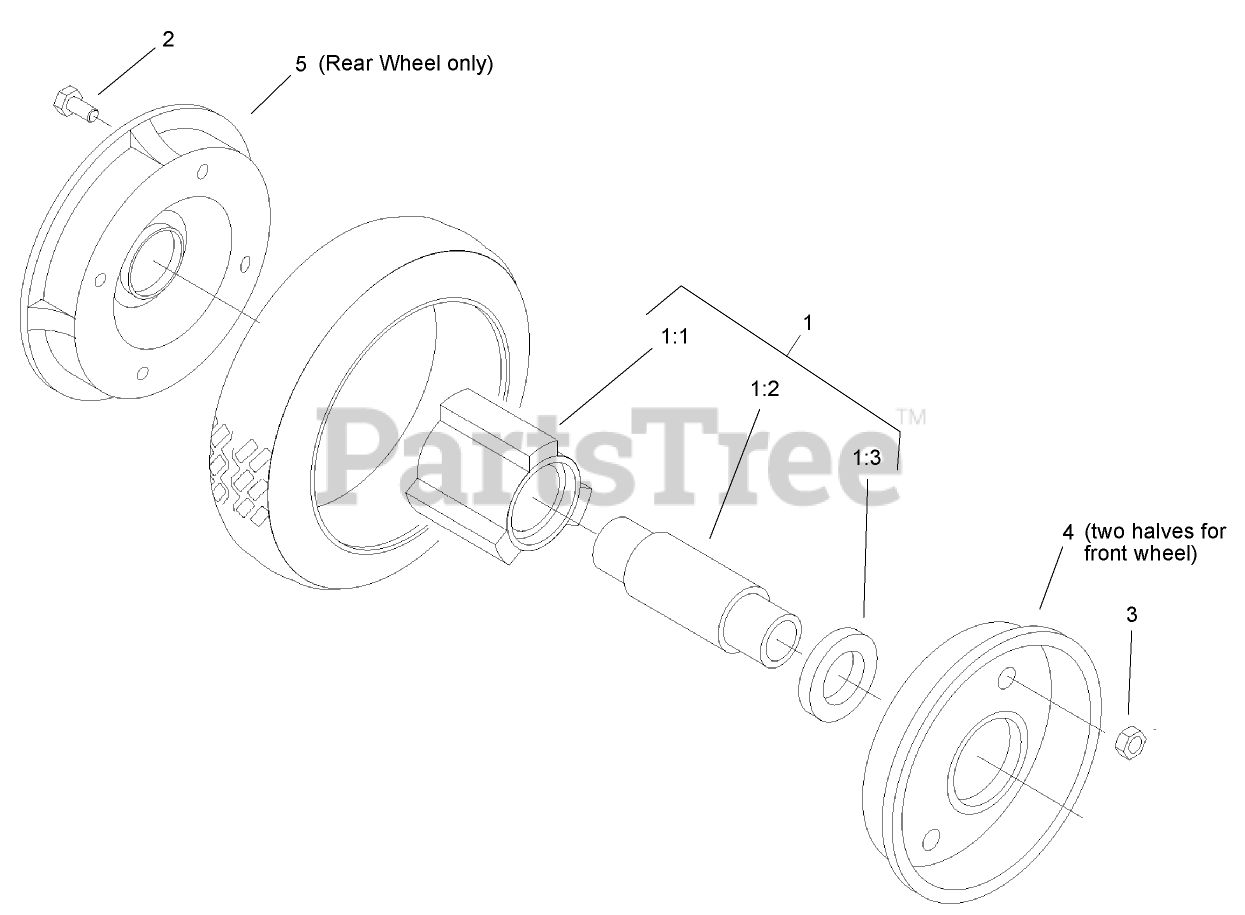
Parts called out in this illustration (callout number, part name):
1	Loose Parts Package
1:1	HUB-BEARING
1:2	SPACER-BEARING
1:3	BEARING-WHEEL
2	SCREW-HH
3	NUT-LOCK, NI
